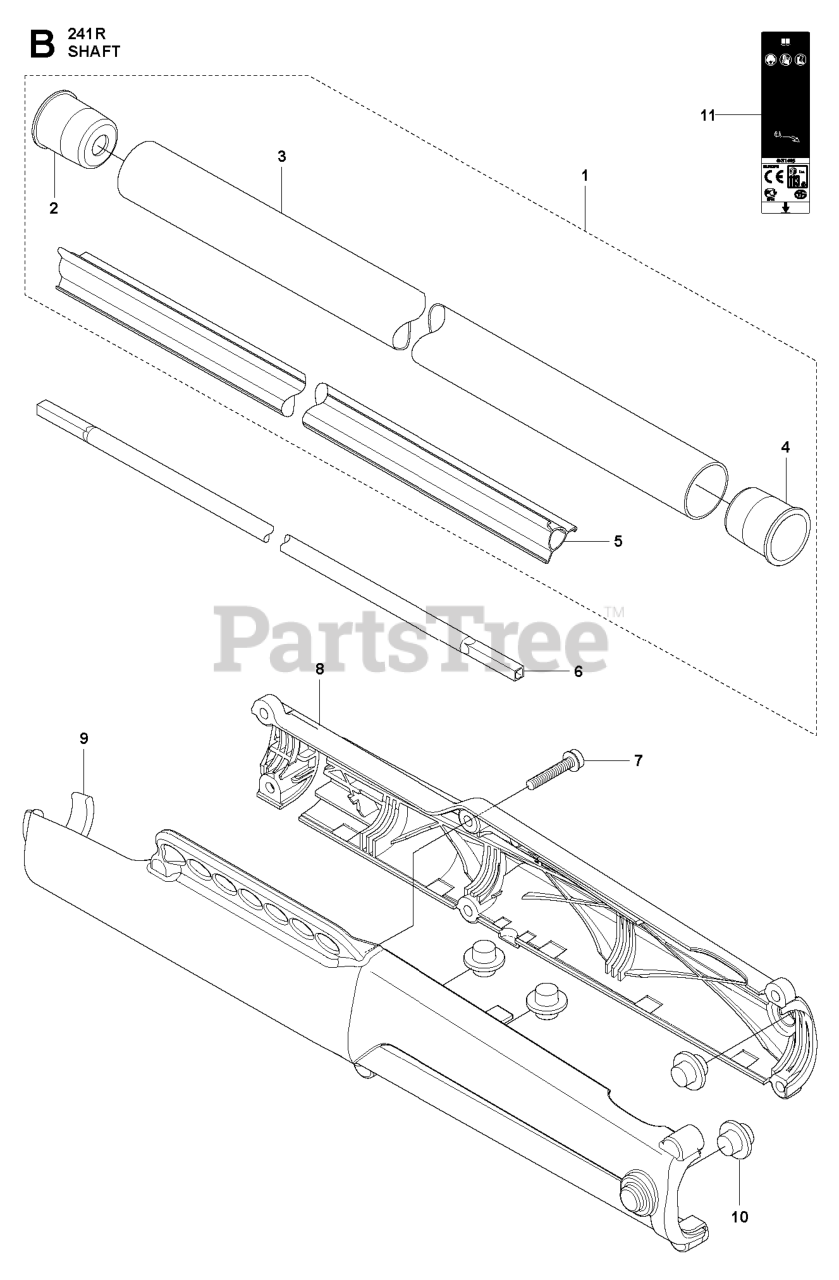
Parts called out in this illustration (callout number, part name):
1	TUBE
2	PLUG
3	TUBE
5	GUIDE
6	SHAFT
7	SCREW IHSCFT
10	VIBRATION ABSORBER
11	LABEL WARNING TRIMMERS AND BRU
